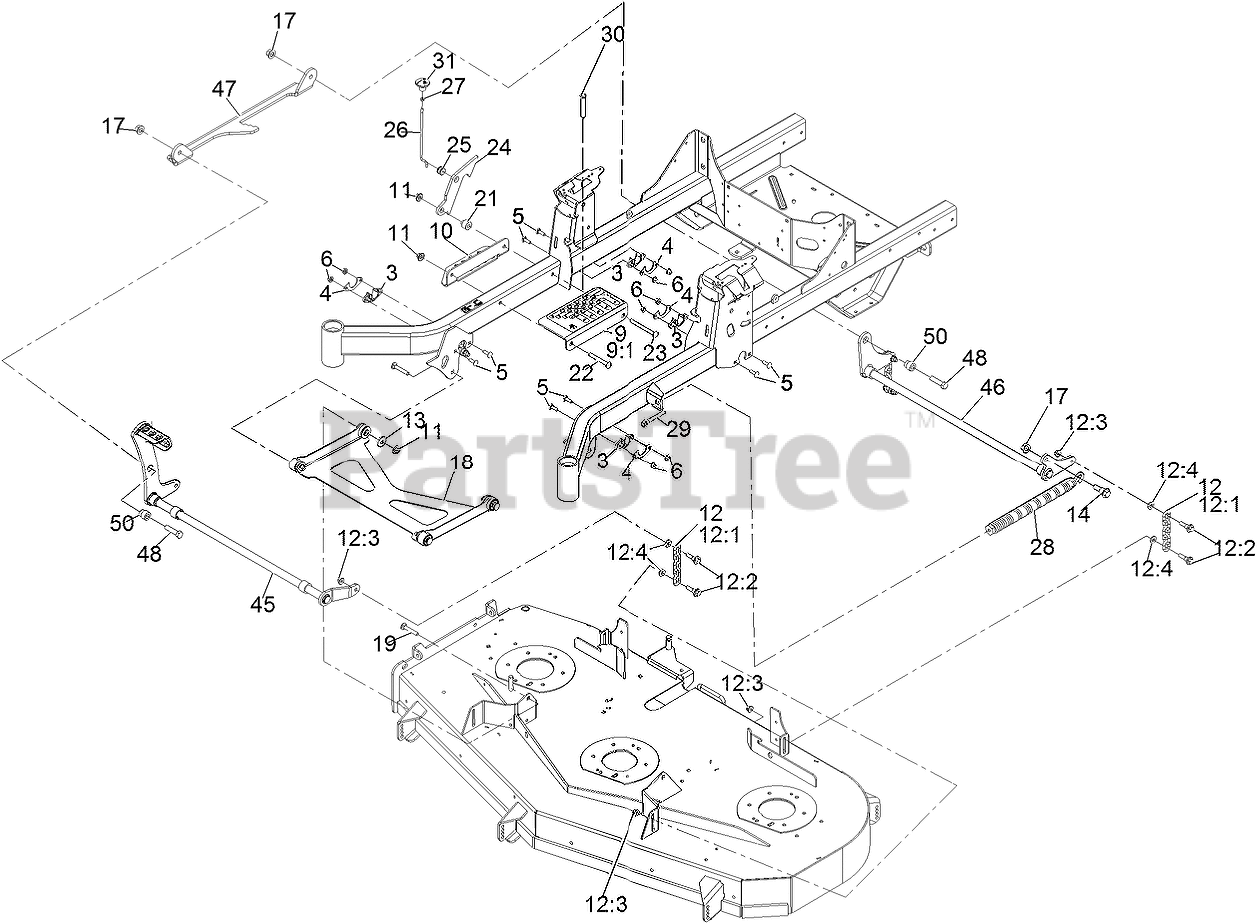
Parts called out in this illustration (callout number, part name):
3	BUSHING-FLANGE
4	GUSSET-LIFT, DECK
5	SCREW-CARR
6	NUT-HF, NI
9	BRACKET ASM
9:1	DECAL-HOC
10	ANGLE-HOC, LOWER
11	Nut-Nyloc 3/8-16 Flg
12	DECK CHAIN ASM
12:1	CHAIN-LIFT, DECK
12:2	BOLT-SHOULDER
12:3	NUT-HF, NI
14	SCREW-SHOULDER, HHF 1/2-13 X 1.12
17	Nut-Lock 1/2-13
18	DECK STRUT ASM
19	Bolt-Carriage 3/8-16 X 2 1/4
21	SPACER-STEPPED
22	SCREW-CARR
23	SCREW-CARR
24	PLATE-LOCK, TRANSPORT
25	GROMMET
26	ROD-LOCK, TRANSPORT
27	NUT-JAM
28	SPRING-EXTENSION
29	BOLT-SHOULDER
30	PIN-HOC
45	Shaft-Decklift Front
46	Shaft-Decklift Rear
47	Link-Decklift
48	SCREW-HH
50	Spacer-Stepped
